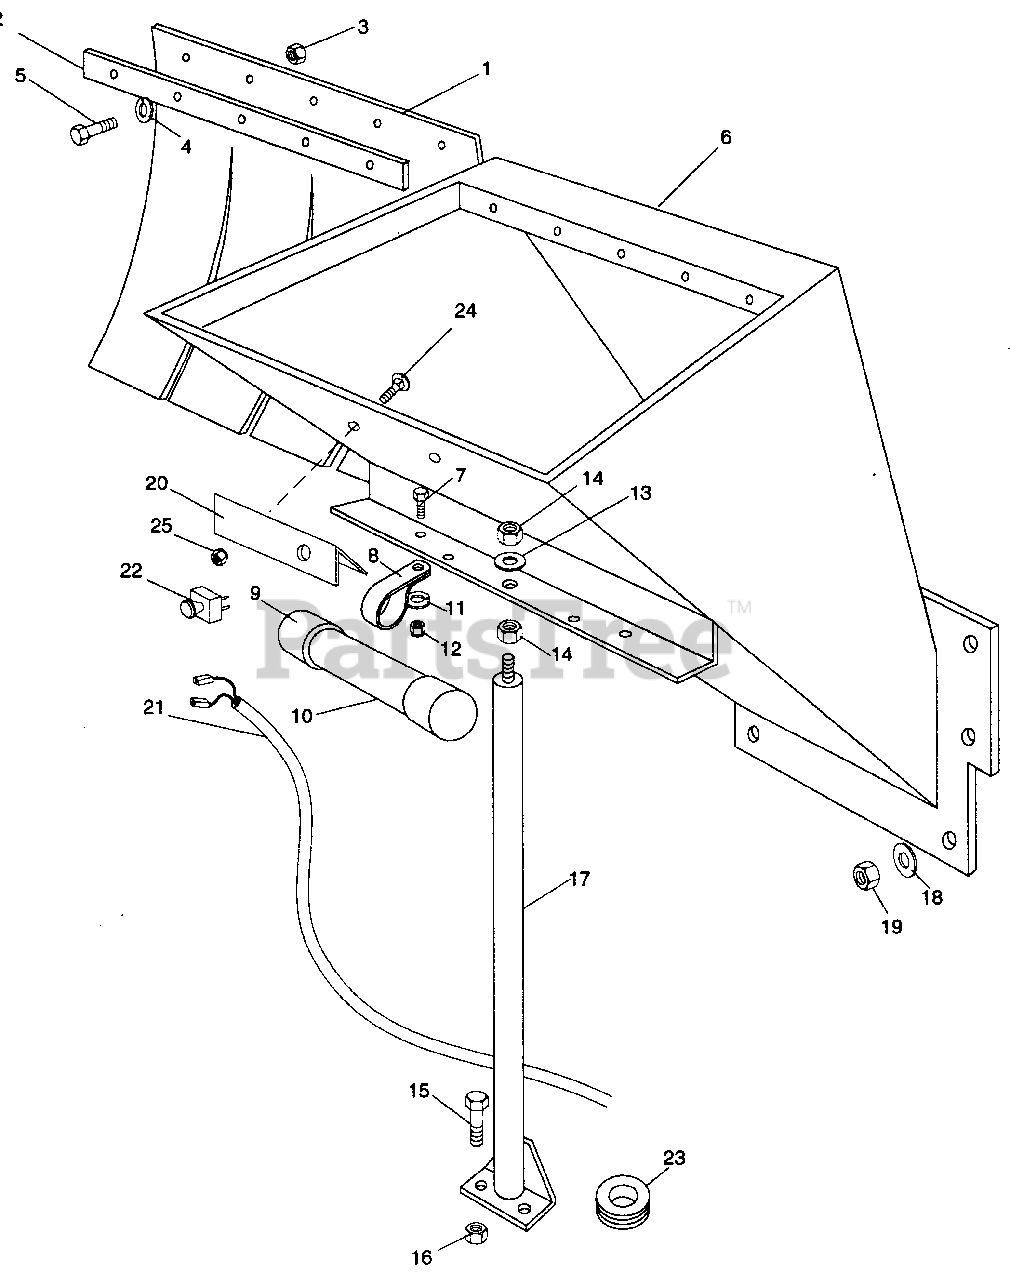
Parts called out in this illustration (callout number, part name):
1	RUBBER FLAP
2	BRACE
3	NUT-LK TOP .250-20 PL
4	WSHR-FL-STL .265X.500X.087 PL
5	BLT-HEX .25-20X.75 PL GR 5
7	BLT-HEX .25-20X.75 PL GR 5
8	CLAMP
9	END CAP INSTRUCTION TUBE
10	PLASTIC TUBE INSTRUCTIONS
11	WSHR-LOCK .250X.007 HVY PL
12	NUT .250-20 PL
13	WSHR-LOCK .750X.188 MED PL
14	NUT-JAM .75-10 PL
15	SCR-TAP .375-16X1.0 HWH PL TR
16	NUT-LK .375-16 GR A PL
17	HOPPER STAND
18	WSHR-FL-STL .406X1.000X.188 PL
19	NUT-LK TOP .375-16 GR C PL
20	MOUNT BRACKET, STOP SWITCH
21	WIRE HARNESS 210 PRO CHIP
22	SWITCH, PUSH/PULL
23	GRMT .75X1.06X1.38
24	BLT-RDHDSQNK .25-20X.38 SHT PL
25	NUT-LK-CTR .250-20 PL
